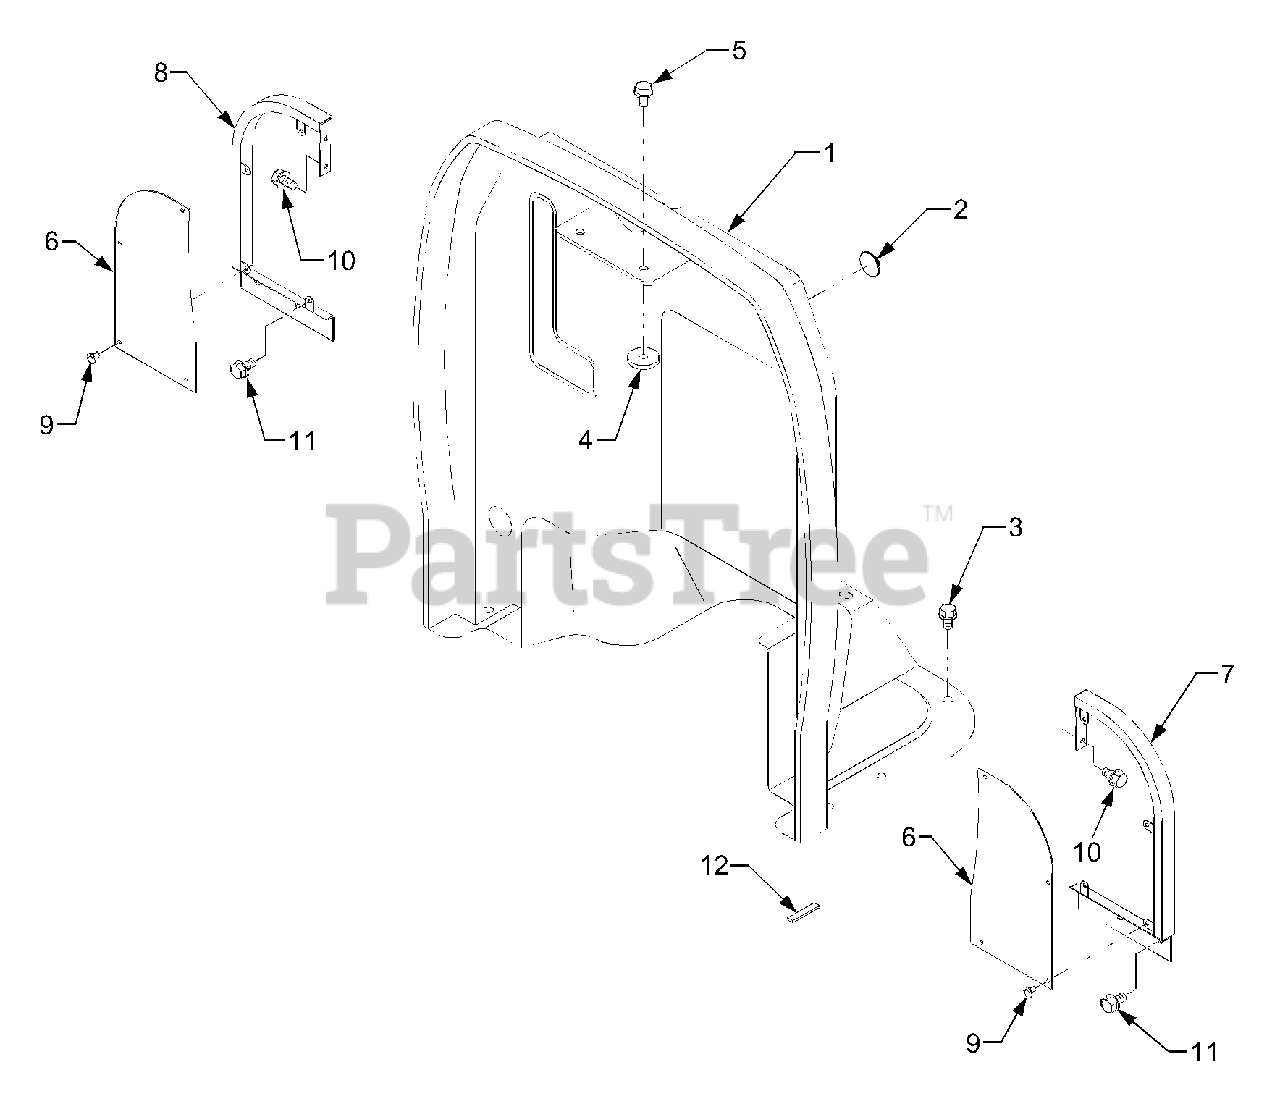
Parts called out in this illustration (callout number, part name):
7	Mudguard Ass'y (LH)
8	Mudguard Ass'y (RH)
12	Rubber, Cushion
